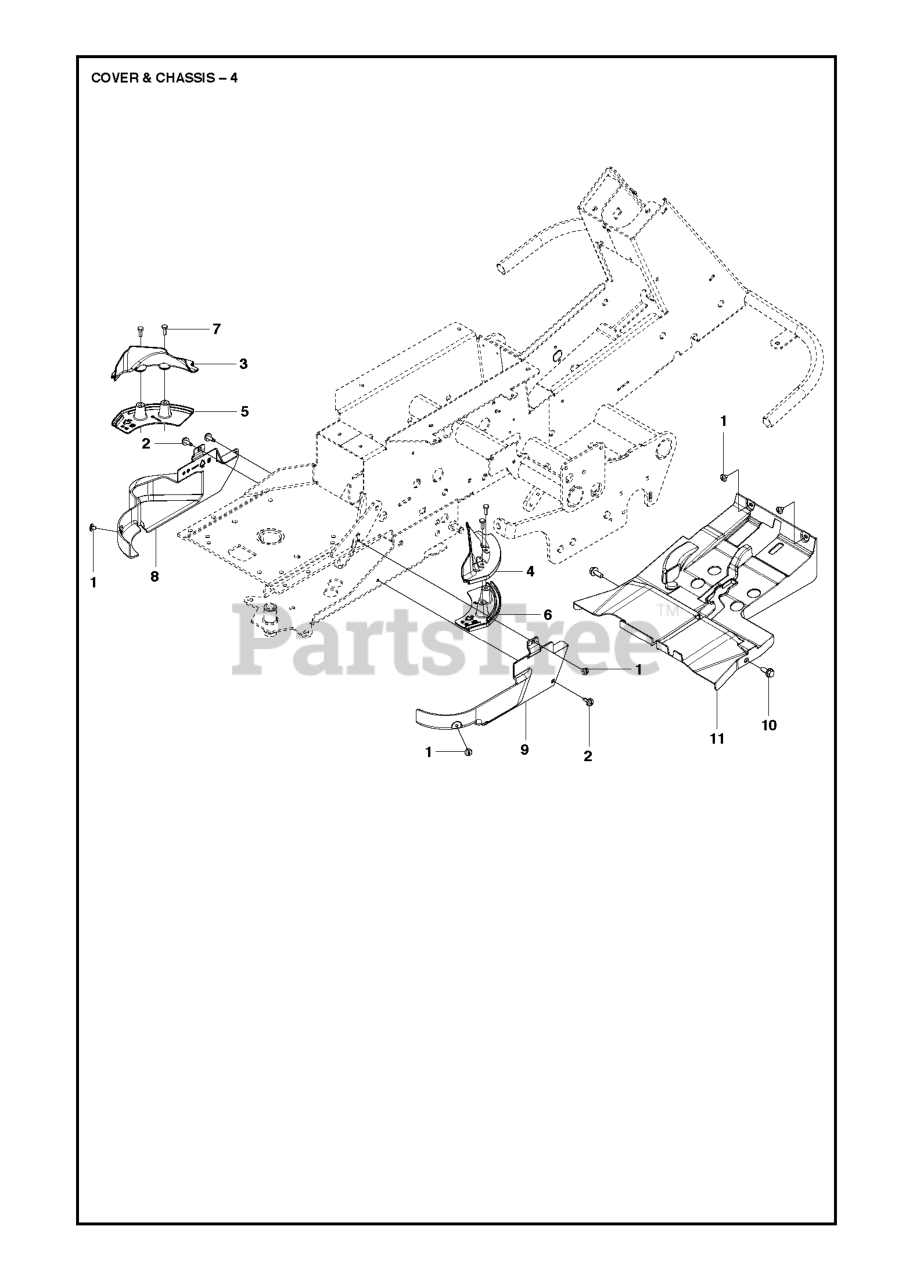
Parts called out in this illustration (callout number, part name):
2	SCREW
7	SCREW
10	BOLT
